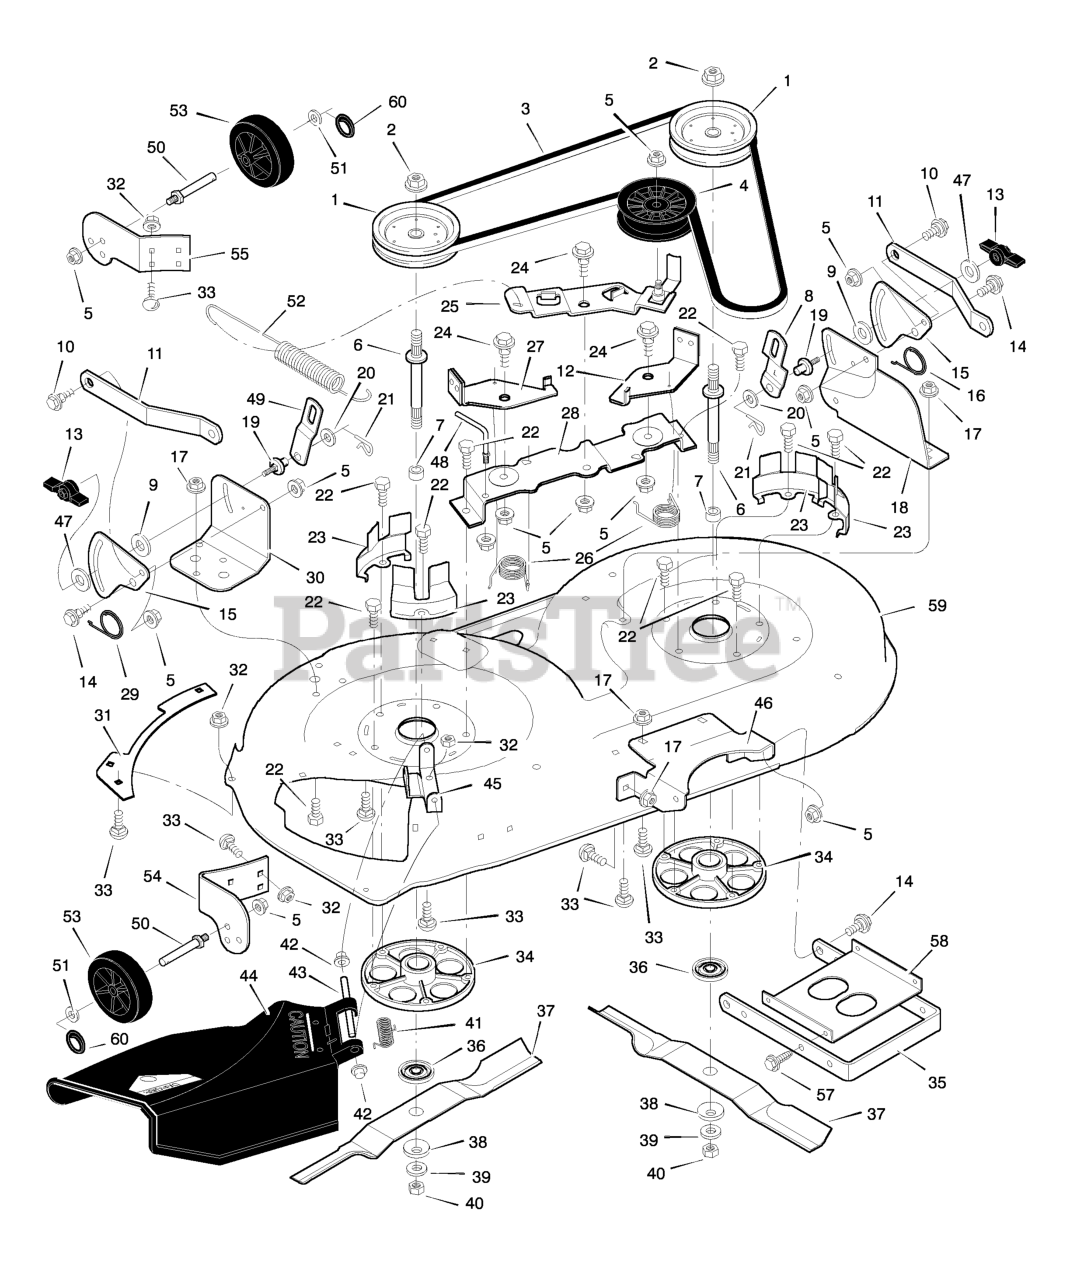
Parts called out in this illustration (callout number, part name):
1	Pulley, Jackshaft
2	Nut, Hex
3	Belt, Mower Drive
4	Pulley, Idler
5	Nut, Flange
6	Jackshaft
8	Link, Left Lift
9	Pad, Friction
10	Bolt, Shoulder
11	Bracket, Suspension
12	Pad Assembly, Left Brake
13	Knob
14	Bolt, Shoulder
15	Plate, Suspension
17	Nut, Flange
18	Bracket, Suspension
19	Pin, Hanger
21	Pin, Hair
22	Bolt
23	Cover, Pulley
24	Bolt, Shoulder
25	Arm, Idler
27	Pad Assembly, Right Brake
28	Bracket, Brake
30	Bracket, Suspension
32	Nut, Flange
33	Bolt, Carriage
34	Mandrell Housing
35	Bracket, Suspension
36	Adapter, Blade
42	Cap, Push On
43	ROD, Deflector
44	Deflector Assembly
45	Bracket, Deflector Hinge
46	Bracket, Front Hanger
48	Guide, Belt
49	Link, Right Lift
50	BOLT, Gauge Wheel
52	Spring, Extension
53	Wheel, Gage
54	Bracket, Right Wheel
55	Bracket, Left Wheel
58	Stiffener
59	Housing, Blade, Complete (NO LONGER AVAILABLE)
59	Housing, Blade (Housing Only)
60	Ring, Locking
